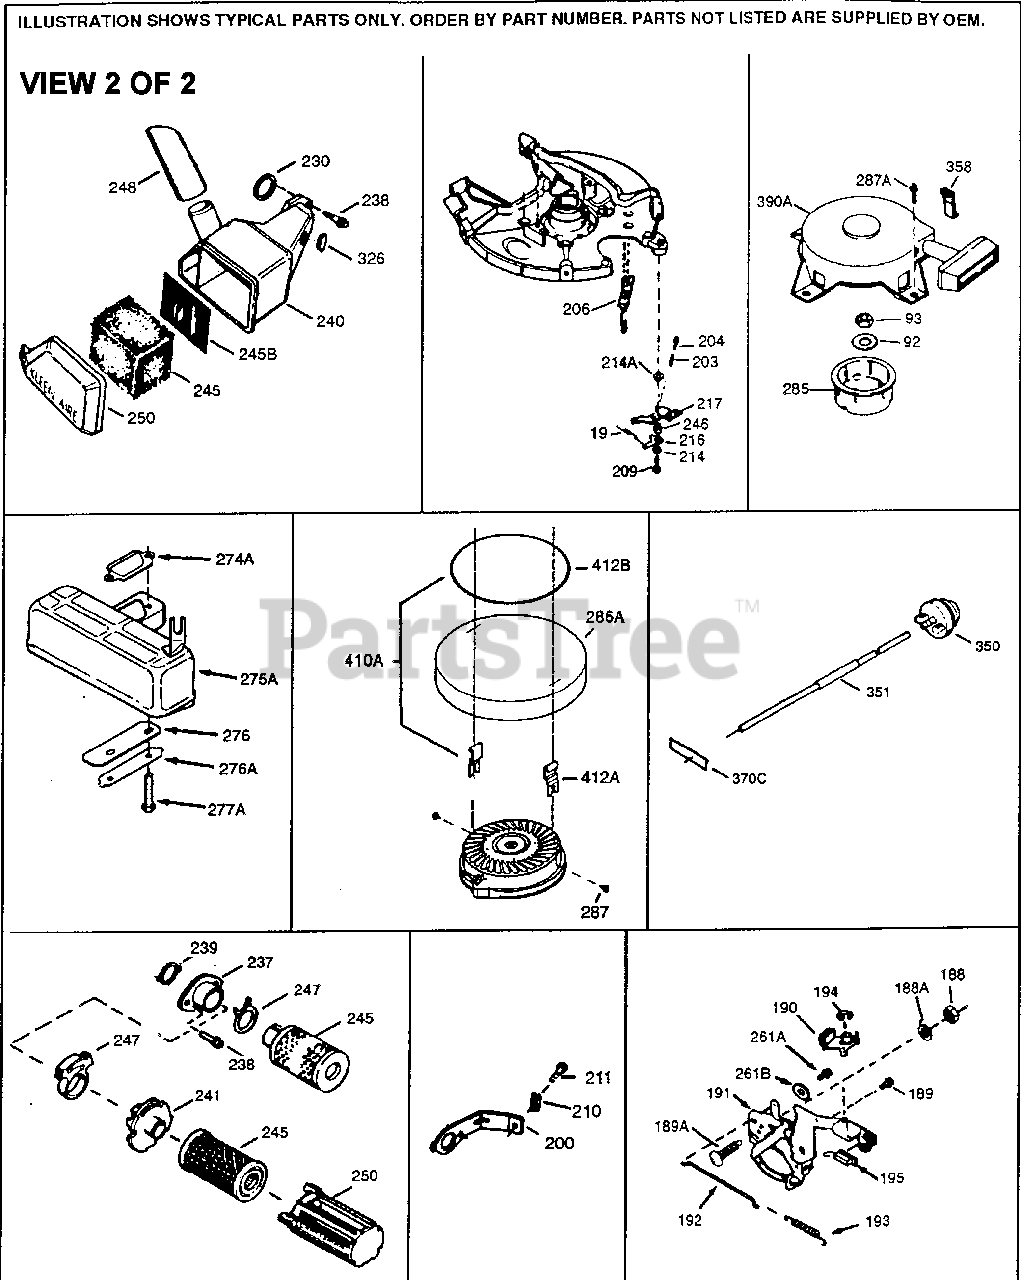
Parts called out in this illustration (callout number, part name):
92	Belleville Washer
93	Flywheel Nut
189	Screw, 1/4-20 x 1/2"
190	Brake Lever
191	S.E. Brake Bracket (Incl. 195)
192	Brake Control Link
193	Brake Spring
194	Retaining Ring
195	Terminal
230	Air Cleaner Gasket
238	Screw, 10-32 x 5/8"
240	Air Cleaner Body
245	Air Filter
245B	Air Filter
248	Air Cleaner Tube
250	Air Cleaner Cover
261A	Screw, 1/4-20 x 1/2"
285	Starter Cup
287	Screw, 8-32 x 21/64"
350	Primer Ass'y.
351	Primer Line
370C	Primer Decal
